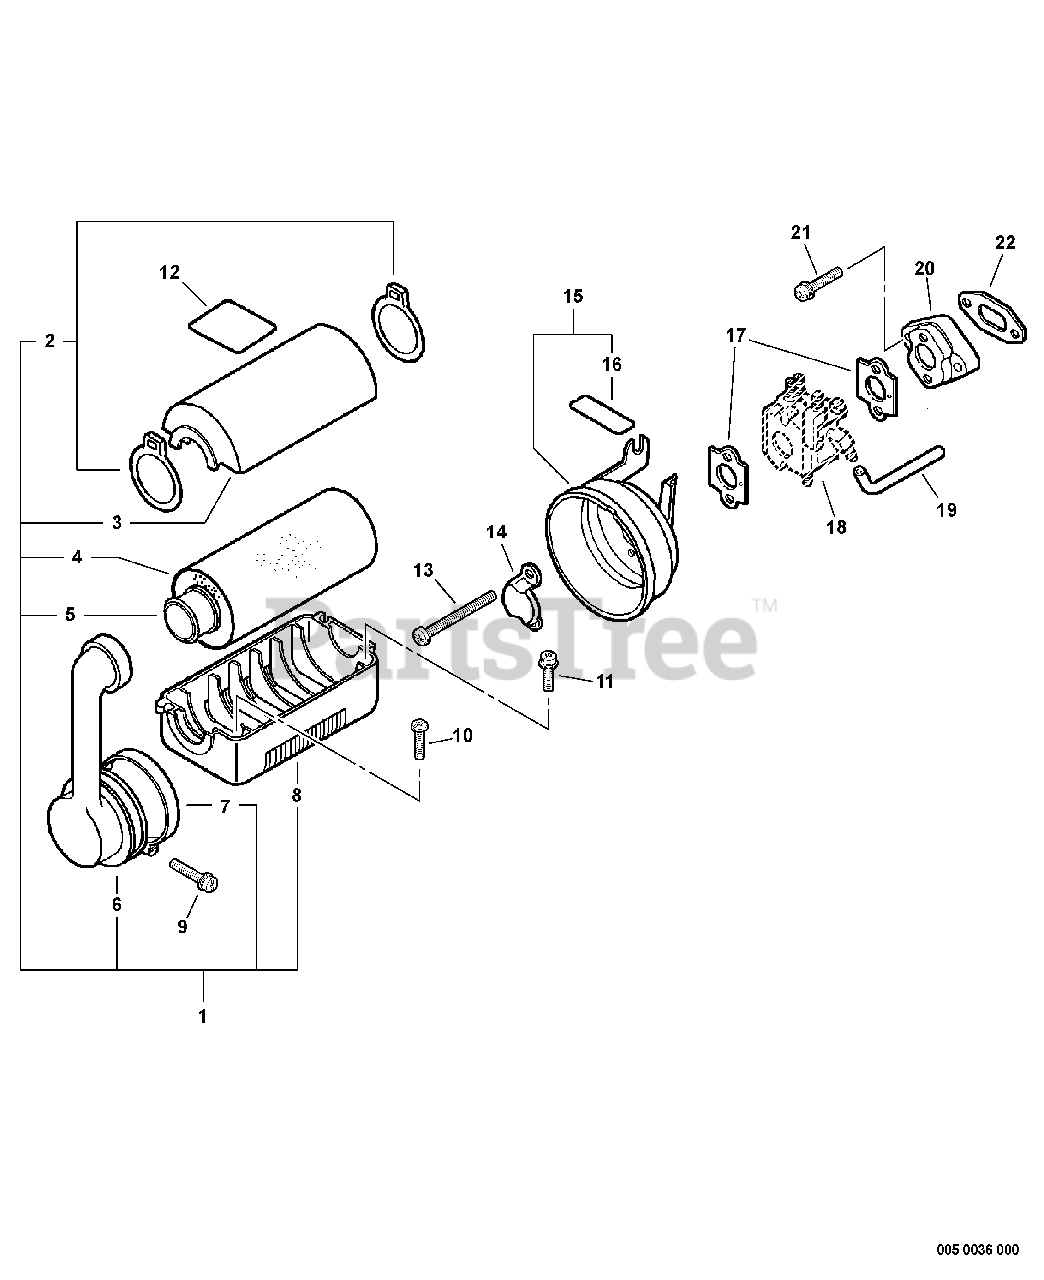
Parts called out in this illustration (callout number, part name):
1	AIR FILTER ASSY
3	COVER, AIR FILTER
4	FILTER, AIR
5	HOLDER, AIR FILTER
6	ADAPTER, INTAKE
8	CASE, AIR FILTER
9	SCREW 5×30
10	SCREW 6×15
11	SCREW 6×20
12	LABEL - CAUTION
13	SCREW 5×50
14	PLATE, PREVENT
15	CASE, AIR FILTER
16	LABEL, CHOKE
17	GASKET, CARBURETOR
18	CARBURETOR
19	PIPE
20	INSULATOR
21	SCREW 6×25
22	GASKET, INTAKE
